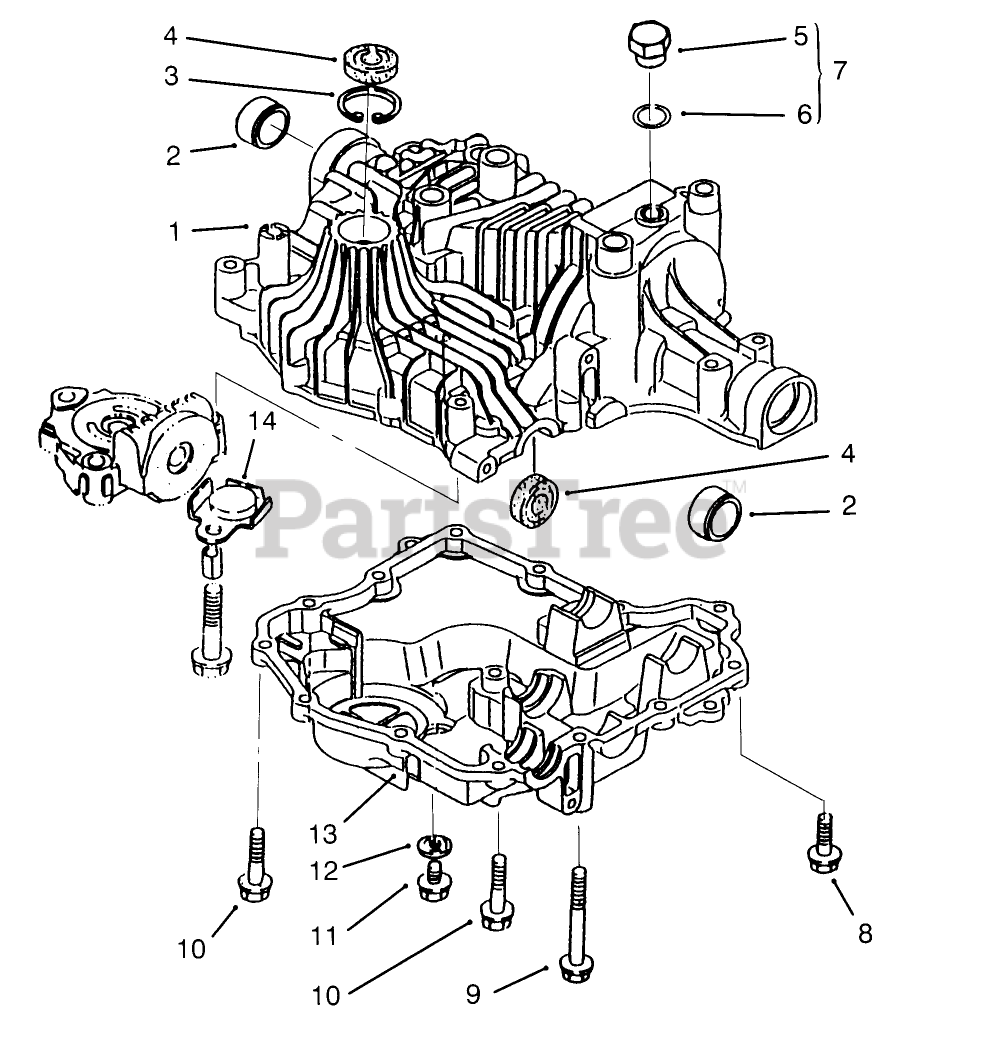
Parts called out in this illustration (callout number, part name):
1	ASM - UPPER CASE INC 2-6
3	RING
4	SEAL
8	SCREW-TAP
10	SCREW-TAP
13	CASE - LOWER
14	MAGNET
